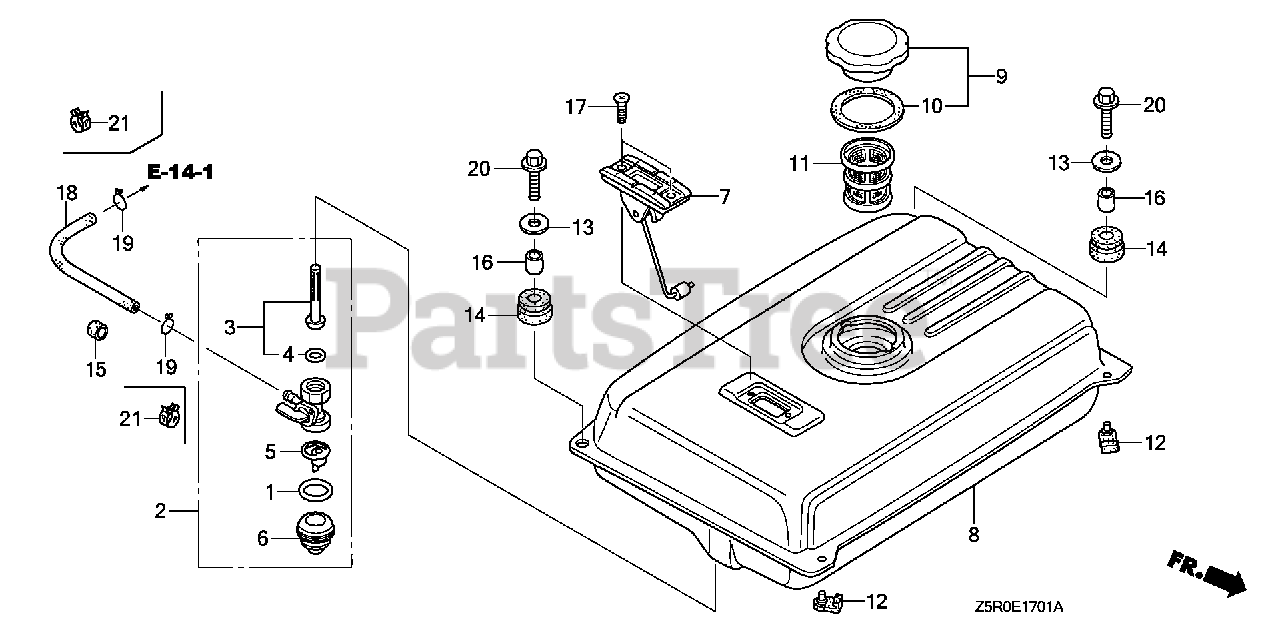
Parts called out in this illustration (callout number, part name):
15	RUBBER, FUEL (9X15X10)
18	TUBE, FUEL (4.5X165) (FKM)
21	CLAMP, TUBE (D8)
